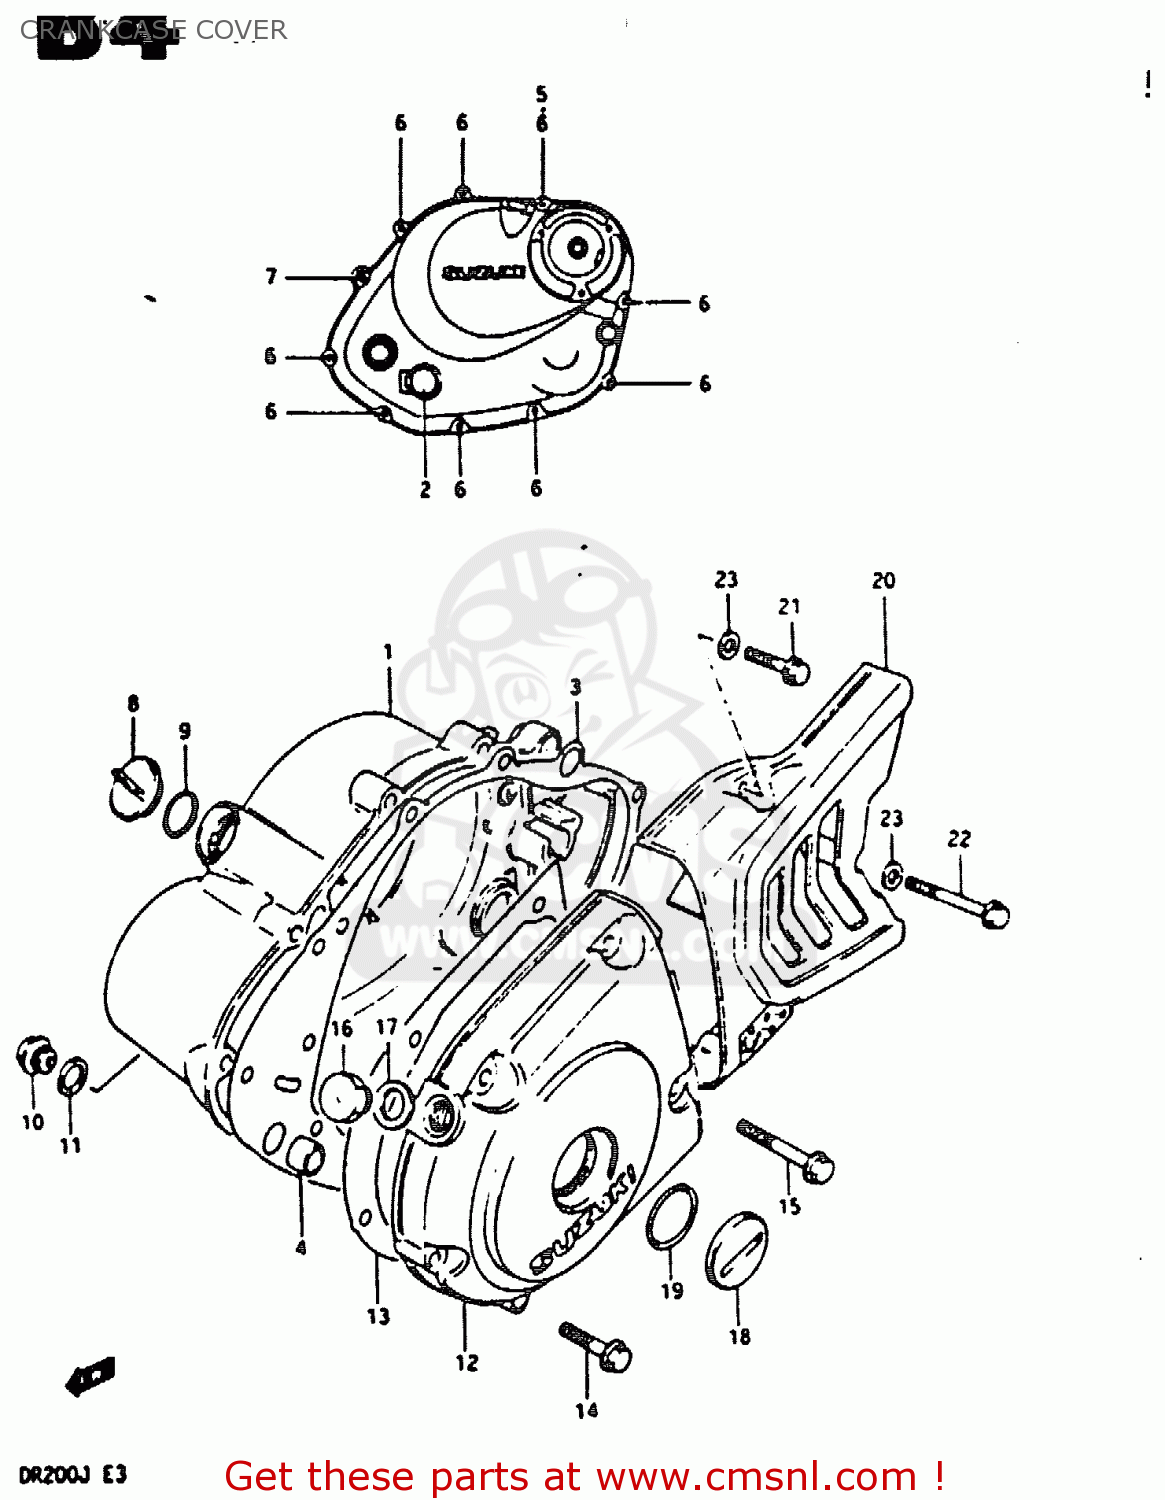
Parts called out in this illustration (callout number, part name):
1	COVER,CLUTCH
2	LENS,OIL LEVEL CHECK
3	GASKET,CLUTCH COVER (MCA)
4	PIN
5	WASHER
6	BOLT 6X30
7	BOLT
8	PLUG
9	O RING(D:3.1,ID:16.8)
10	PLUG(14X12)
11	GASKET(14X19.2X2) (NAS)
12	COVER,MAGNETO
13	GASKET,MAGNETO COVER (MCA)
14	BOLT 6X30
15	BOLT 6X40
16	PLUG(12X9)
17	GASKET(12.1X16.2X3.7) (NAS)
18	PLUG
19	O RING(D:3.1,ID:22.7)
20	COVER,SPROCKET
21	BOLT
22	BOLT
23	WASHER,5MM
